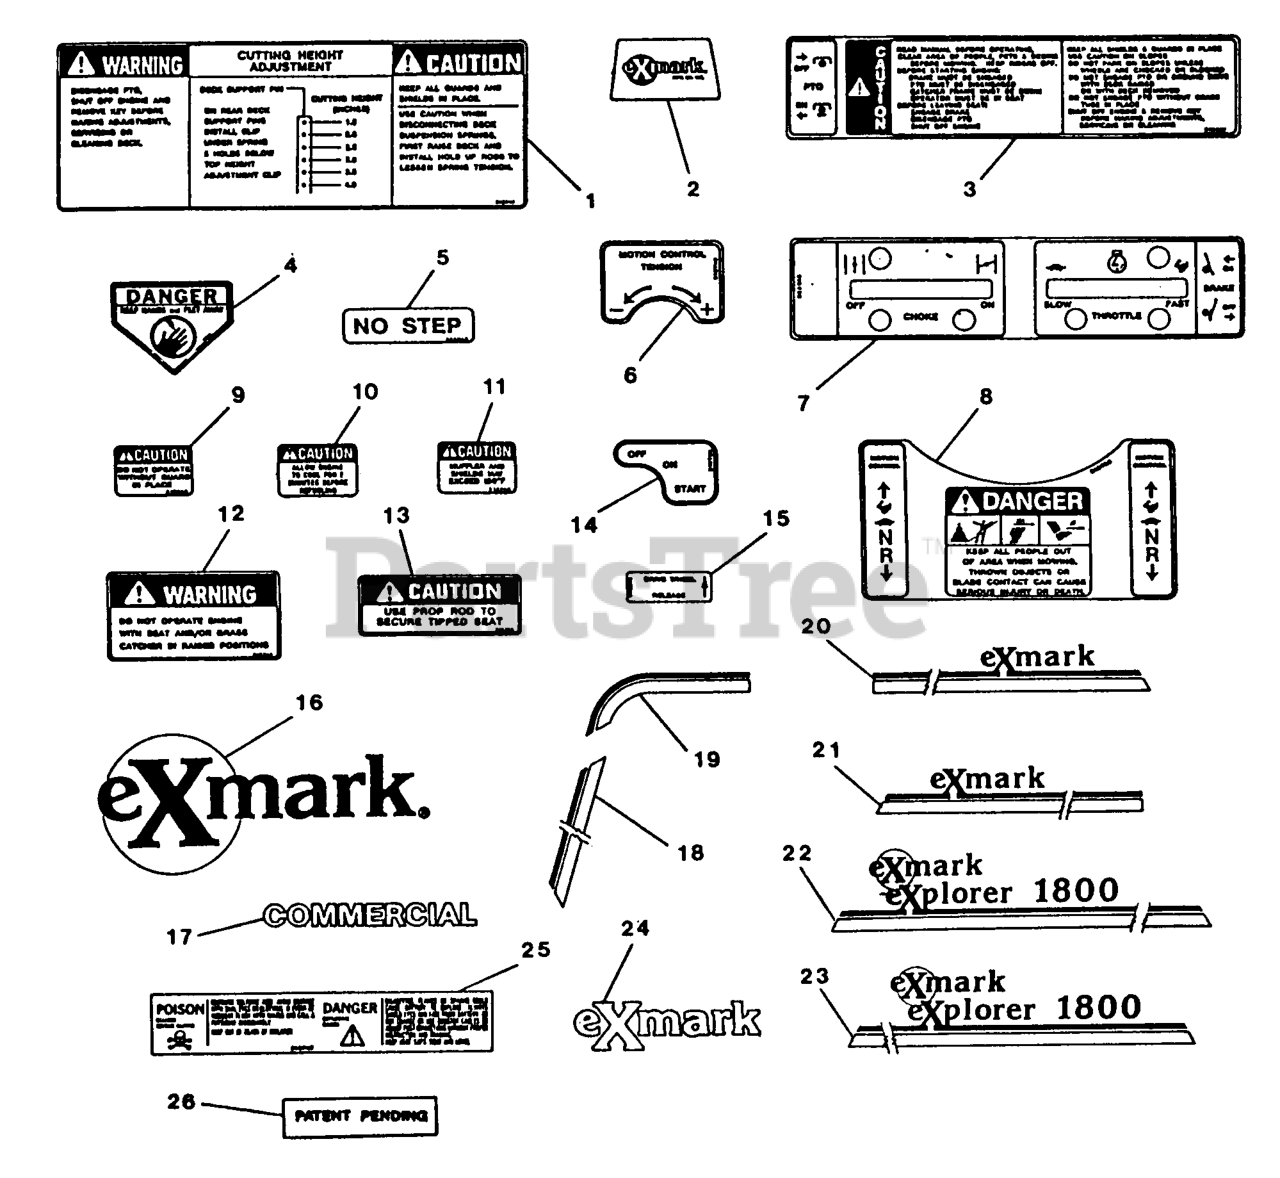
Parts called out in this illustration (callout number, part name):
3	DECAL,FENDER RH
4	DECAL-DANGER
5	DECAL,NO STEP
8	DECAL,CONSOLE
9	DECAL-GUARD
25	DECAL-BATTERY
26	Decal - Patent Pending
